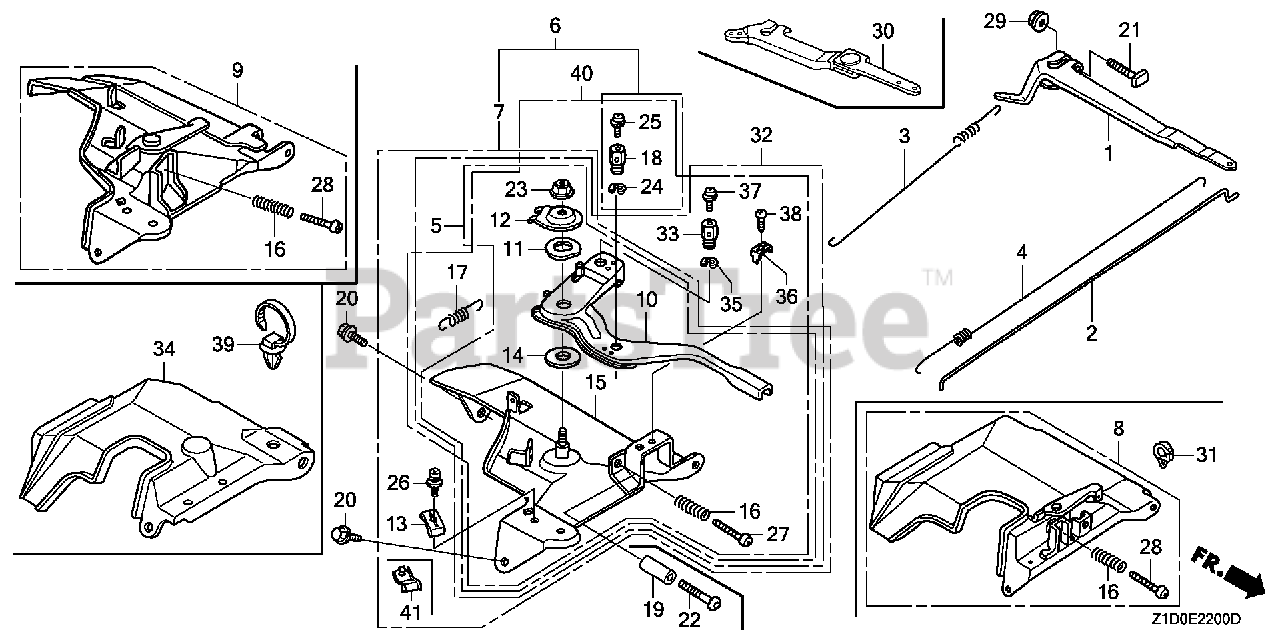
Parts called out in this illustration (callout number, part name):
1	ARM, GOVERNOR
2	ROD, GOVERNOR
3	SPRING, GOVERNOR (L=145.0MM) (WIRE DIAMETER 1.0MM)
4	SPRING, THROTTLE RETURN
9	CONTROL ASSY. (COO)(FOR U.S.A.)
9	CONTROL ASSY.
16	SPRING, CONTROL ADJUSTING
20	BOLT, FLANGE (6X12) (CT200)
21	BOLT, GOVERNOR ARM
28	SCREW, PAN (5X35)
29	NUT, FLANGE (6MM)
